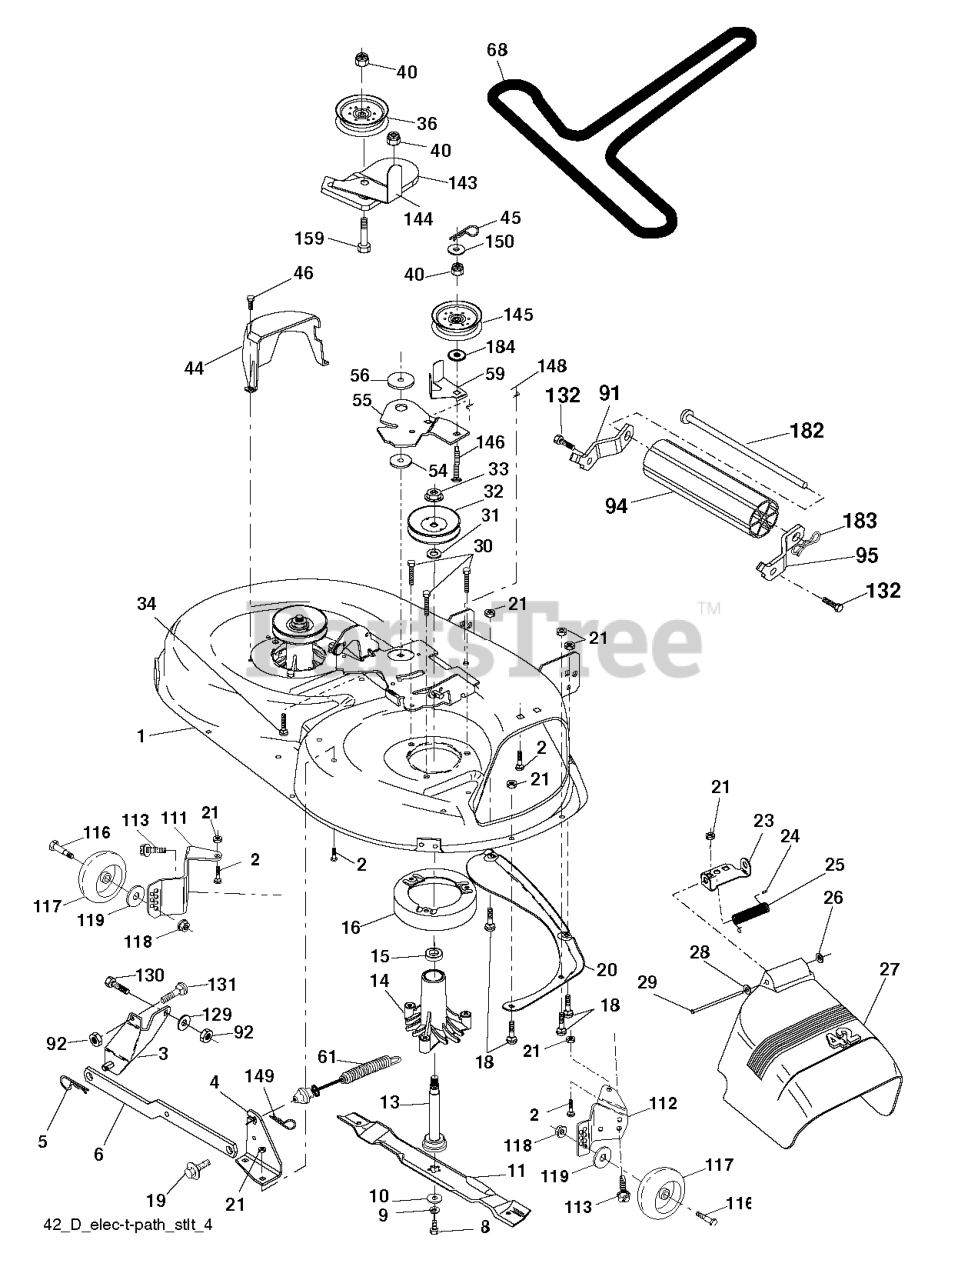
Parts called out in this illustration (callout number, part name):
1	42" DECK KIT
2	RP BOLT 5/16-18 X3/4 ZN/YEL GR
3	BRKT ASM SWAY BAR
4	BRACKET SWAY BAR 42" DECK
5	RETAINER-SPRNG RB
6	BAR SWAY DECK
8	BLADE BOLT
9	LOCKWASHER
10	WASHER.BLADE
11	42" HI-LIFT BLADE
13	SHAFT ASM VENT
14	HOUSING.MANDREL.VENTED (MACHD)
16	STRIPPER.MANDREL.ROUND.BLACK
18	BOLT
19	BOLT SHD 5/16-18
20	BAFFLE.VORTEX
21	LOCKNUT
23	BRKT, DEFL. MOWER
24	CAP-SLEEVE LT
25	SPRING TORSION
26	NUT PUSH M
27	SHIELD DEFLECTOR
28	Washer 11/32 x 5/8 x 16 Ga SD
29	ROD.HINGE
30	SCREW, WASHER HEAD
31	WASHER.SPACER.MANDREL
32	PULLEY/MANDREL
33	NUT.FLANGE.LOCK.TOP
34	BOLT.3/8-16X1.50
36	FLAT IDLER PULLEY
40	NUT LOCK FLG 3/8-16 UNC
44	GUARD MANDREL LH BLACK
45	RETAINER M
46	SCREW.1/4-20X5/8
55	ARM IDLER 42" MOWER LT/YT
56	SPACER.RETAINER.MOWER
59	GUARD, BELT
61	SPRING EXT ELEC CLUTCH
68	V-BELT PRIMARY 42"
91	BRACKET ASM NOSEROLLER LH
92	NUT
94	NOSE ROLLER
95	BRACKET ASM NOSEROLLER RH
111	BRACKET, WHEEL
112	BRACKET, WHEEL
113	BOLT.5/16HEX.WHS.HD
116	BOLT M
117	WHEEL.GAGE.HALF.SPOKED
118	LOCKNUT
119	WASHER.5/16.FLAT.STE.STD.
129	WASHER
131	BOLT D
132	SCREW, 3/8-16X3/4
143	BRACKET, ARM IDLER
144	DNO KEEPER.BELT.42".CLUTCH.CBL
145	PULLEY
146	BOLT, CARRIAGE IDLER BLACK
148	IDLER RETURN SPRING
149	SPRING.RETAINER.YELLOW.ZINC
182	ROD ROLLER NOSE STANDARD
183	PIN.COTTER.7/16.BOW TI.
184	WASHER
